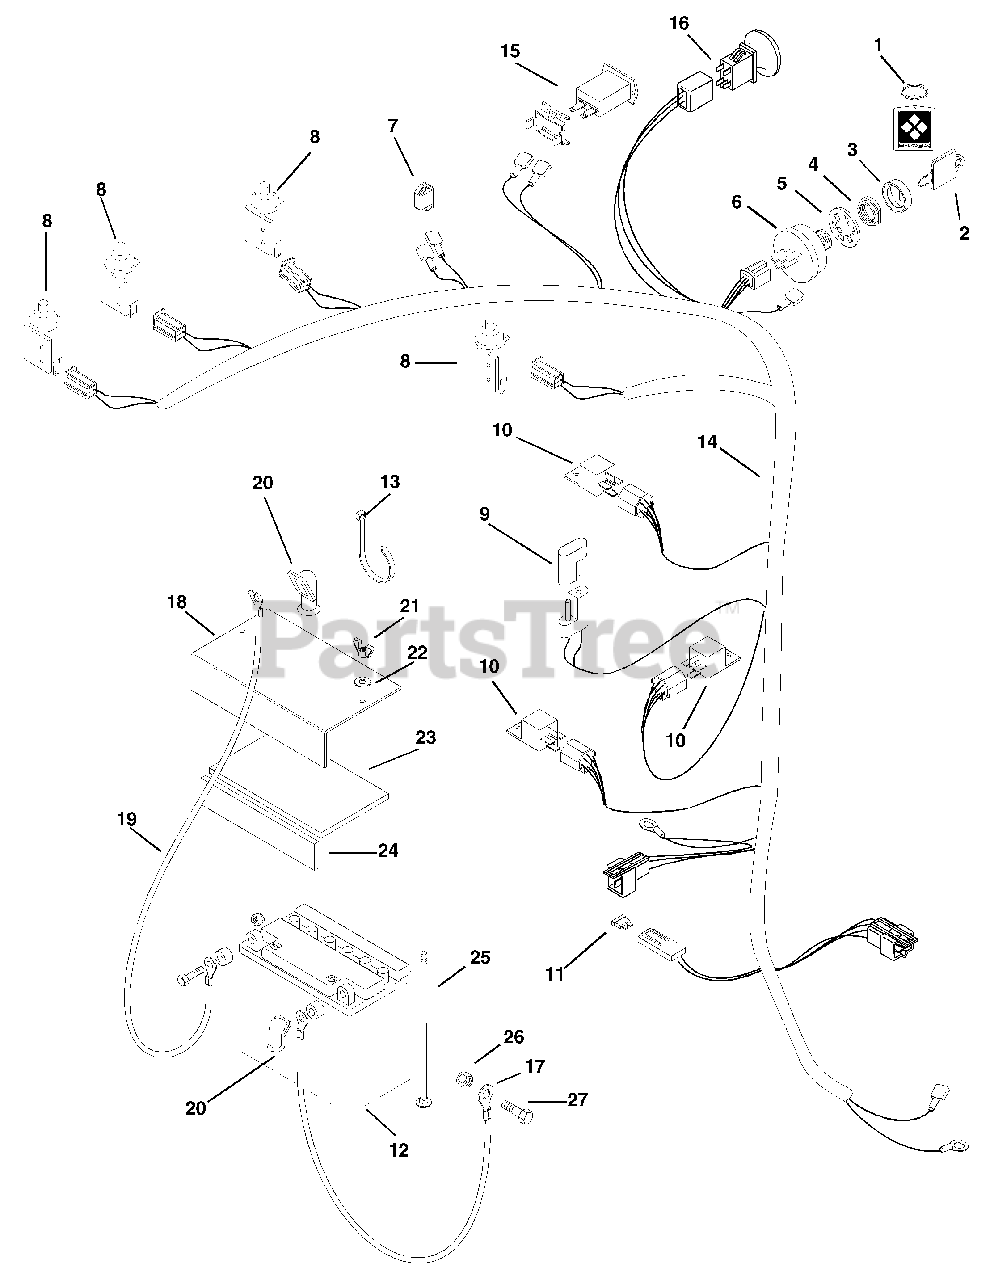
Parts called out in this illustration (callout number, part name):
1	KEY CHAIN
2	KEY -W/CAP
3	CAP - IGNITION SWITCH
4	NUT-PANEL .625-32 GRECO
5	WSHR-LK-INT .625X.045 PL
6	KEY SWITCH
7	LIGHT, INDICATOR (RED)
8	SWITCH-SINGLE POLE N.O.W/COVER
9	MOLDED DIODE PLUG 1 AMP
10	RELAY
11	FUSE, 30 AMP.
12	BATTERY,12 VOLT
13	TIE WRAP, BLACK LG 7.31
14	WIRE HARNESS
15	METER, HOUR W/MAINTENANCE
16	SWITCH, CLUTCH
17	CBL,NEGATIVE BATTERY 20.00
18	CVR,BATTERY
19	CBL,BATTERY TO SOLENOID
20	BOOT, INSULATOR
21	NUT-LK WING .250-20 YWZC
22	@WSHR-FL-STL.281X.62X.065 YWZC
23	PAD,BATTERY
24	PAD,BATTERY
25	@BLT-RDHDSQNK .25-20X7.00 G2YZ
26	@NUT-LK-CTR .31-18 YWZC
27	@BLT-HEX .31-18X1.00 GR5 YWZC
